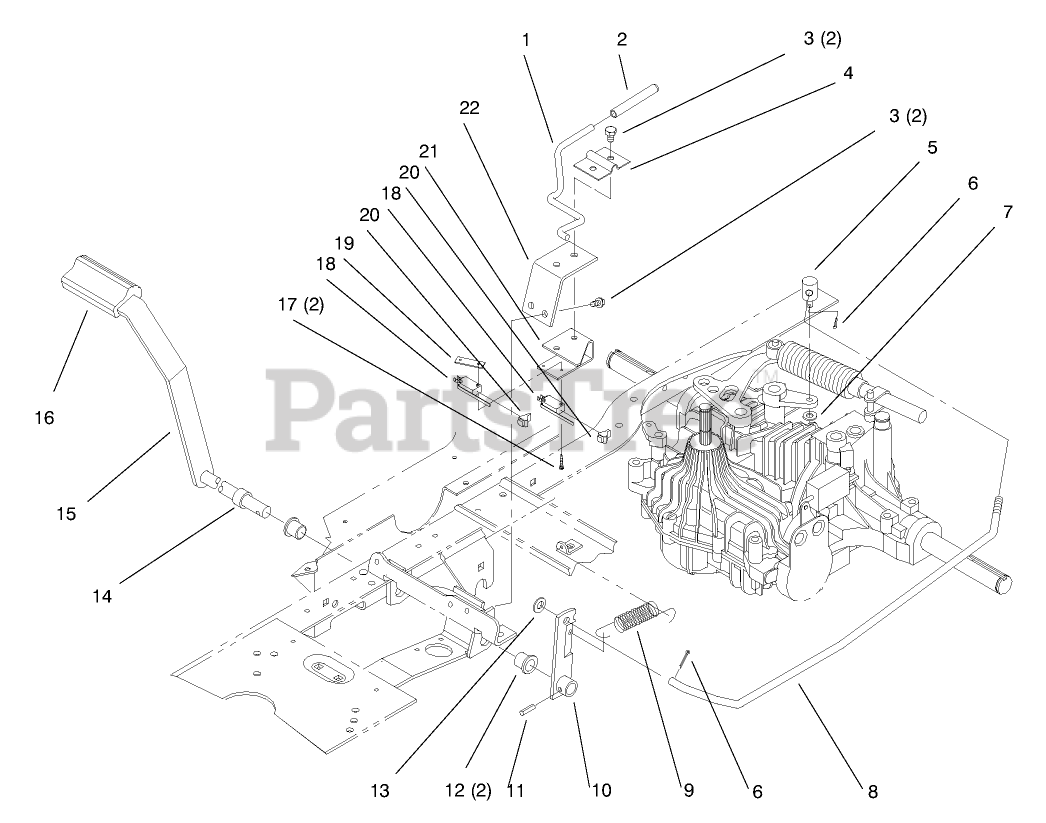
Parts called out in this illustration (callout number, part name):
1	ROD - PARKING BRAKE
2	GRIP - PARKING BRAKE
3	SCREW-HWHTF
4	BRACKET-PARKING BRAKE
5	TRUNNION - BRAKE
6	PIN-COTTER
7	WASHER-PLAIN
10	BRAKE LEVER ASM
11	PIN-SPRING
12	BUSHING-FLANGE
13	WASHER-FLAT
14	SPACER-BRAKE
15	LEVER - BRAKE ASM
16	PAD-PEDAL
17	SCREW-HH
18	SWITCH-MICRO
19	NUT-SPEED
20	PLUNGER-SEAL
21	BRACKET-BRAKE SWITCH
22	SUPPORT-P. BRAKE
